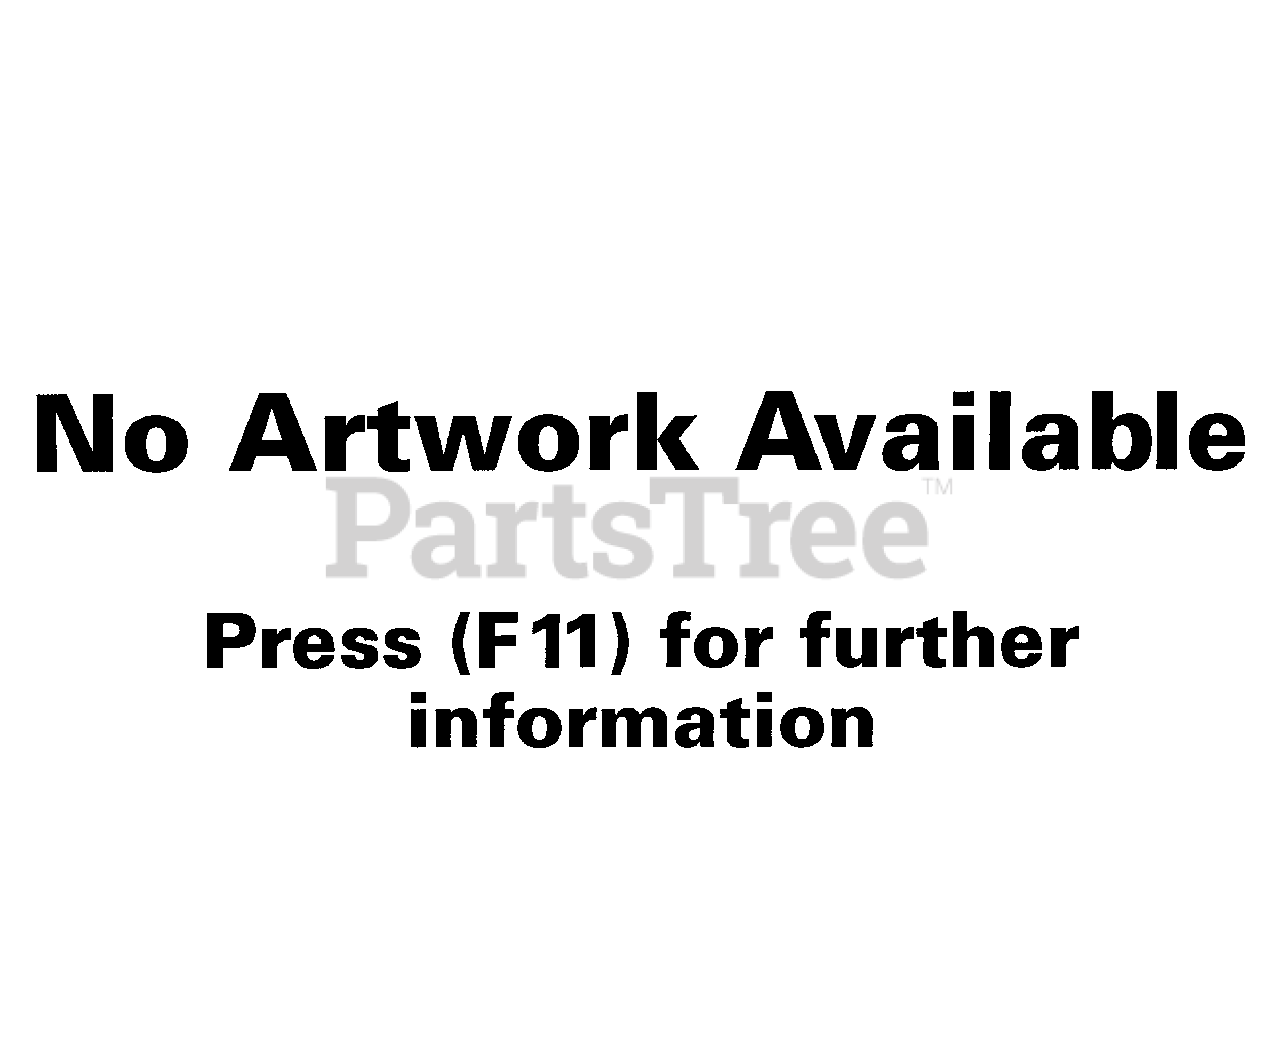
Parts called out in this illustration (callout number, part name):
1	CHAIN GUARD
2	CHAIN GUARD
4	SPROCKET & HUB
6	CLUTCH DISC
7	SPROCKET ASSEMBLY
8	BSHG-SLV 3.000X3.50X.50X3.506
9	OUTER DISC
10	BELLIEVILLE WASHER
13	CHAIN TIGHTNER
14	SG-COMP .075X.22X2.38
15	SPROCKET
16	AUGER DRIVE CHAIN
17	SPACER .760X1.000X.187
18	RVT-POP.187X.277 DOME ST
19	BLT-HEX .31-18X.50 GR5
20	WSHR-LK .312X.097 PL HVY
21	SET SCREW
22	KEY-STR .25X1.75X.25
23	NUT-LK .375-16 PL
24	BLT-HEX .31-18X2.25 PL GR5
25	WSHR-FL-STL.344X.688X.065PL
26	NUT-LK .312-18 GR A PL
27	PIN-COTR .12X.75 PL
28	SCR-SET .32-18X.50 SKH
29	KEY-SQ .188X1.0X.188 SAE 8630
31	KEY-SQ .188X1.5X.187 SAE 8630
32	REAR PTO KIT
33	IDLER-FLAT 4.0 X .50
34	BLT-HEX .50-13X2.50 PL GR5
35	SPACER .510X.750X.750
37	WSHR-FL-STL .531X1.062X.095 PL
38	BELT SHIELD
39	PIN-ROLL .313X.75
40	BELT GUIDE
41	BLT-RDHDSQNK .38-16X1.0 GR5PL
42	WSHR-FL-STL .390X.750X.125 PL
43	IDLER ARM
44	CLUTCH ROD
45	NUT-HEX .375-16
47	BLT-HEX .25-20X.75 PL GR5
48	NUT-LK TOP .250-20 PL
49	V-BELT, HA-WRAPPED (SET)
52	SG-COMP .090X.75X1.125
53	SPACER .384X.500X1.500
54	SPACER .384X.502X.840
55	BRACKET
57	BELT GUIDE
58	WSHR-FL-STL .438X1.0X.083 PL
59	WSHR-FL-STL .38X.875X.083 PL
60	SPACER .423X.675X2.125
61	BLT-HEX .38-16X2.25 GR2
62	WSHR-LK .375X.115 HVY PL
63	PIN-COTR .18X1.50 PL
64	SPACER-SPECIAL CONICAL
65	WSHR-FL-STL .755X1.375X.125 PL
67	BLT-HEX .38-16X2.75 PL GR5
68	SCR-MCH .31-18X1.00 SLFL PL
69	NUT-CROWN .312-18 PL
71	NUT-LK-CTR .50-13
